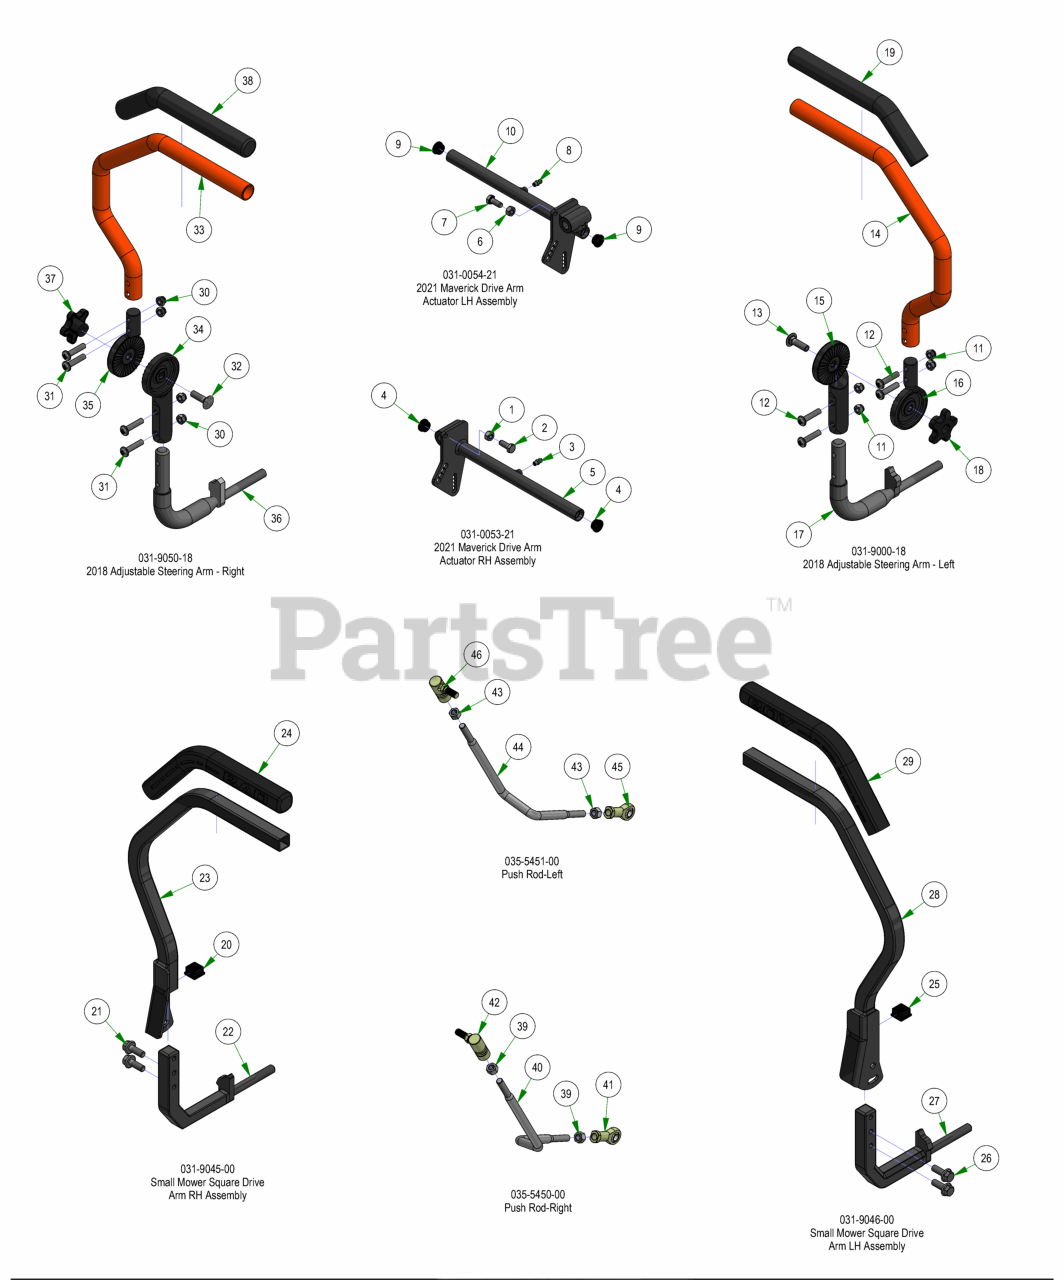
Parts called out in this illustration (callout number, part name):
1	5/16-18 HEX NUT ZINC
2	5/16-18 X 3/4 HEX CAP SCREW (GR.5) ZINC
3	1/4 DRIVE-TYPE STRAIGHT GREASE FITTING ZINC YELLOW)
4	2019 Drive Arm Bushing
5	2021 Drive Actuator RH Weldment
6	5/16-18 HEX NUT ZINC
7	5/16-18 X 3/4 HEX CAP SCREW (GR.5) ZINC
8	1/4 DRIVE-TYPE STRAIGHT GREASE FITTING ZINC YELLOW)
9	2019 Drive Arm Bushing
10	2021 Drive Actuator LH Weldment
11	5/16-18 NYL INS L/N ZC
12	5/16-18 x 1 3/8" Button Head Torx Drive Bolt
13	3/8-16 X 1-1/4 CARRIAGE BOLT ZINC
14	Upper Tube-Adjustable Steering
15	2018 Lower Adjuster - Steering Arm- Left
16	2018 Upper Adjuster - Steering Arm- Left
17	Steering Arm Elbow (Left)
18	Black Knob for Adjustable Steering Arm
19	Rubber Grip
20	9565K16_Polyethylene Square Plug
21	92323A554_Grade 5 Steel Serrated-Flange Hex Head Screw
22	Small Mower Square Drive Arm Lower RH Weldment
23	Small Mower Square Drive Arm RH Weldment
24	Grip for 031-9045-00 / 031-9046-00
25	9565K16_Polyethylene Square Plug
26	92323A554_Grade 5 Steel Serrated-Flange Hex Head Screw
27	Small Mower Square Drive Arm Lower LH Weldment
28	Small Mower Square Drive Arm LH Weldment
29	Grip for 031-9045-00 / 031-9046-00
30	5/16-18 NYL INS L/N ZC
31	5/16-18 x 1 3/8" Button Head Torx Drive Bolt
32	3/8-16 X 1-1/4 CARRIAGE BOLT ZINC
33	Upper Tube-Adjustable Steering
34	2018 Lower Adjuster - Steering Arm- Right
35	2018 Upper Adjuster - Steering Arm- Right
36	Steering Arm Elbow (Right)
37	Black Knob for Adjustable Steering Arm
38	Rubber Grip
39	3/8" Fine Threaded Jam Nut
40	Push Rod - Right (Rod Only)
41	Spherical Rod End - Outlaw
42	Quick Release Ball Joint
43	3/8" Fine Threaded Jam Nut
44	Push Rod LH (Rod Only)
45	Spherical Rod End - Outlaw
46	Quick Release Ball Joint
